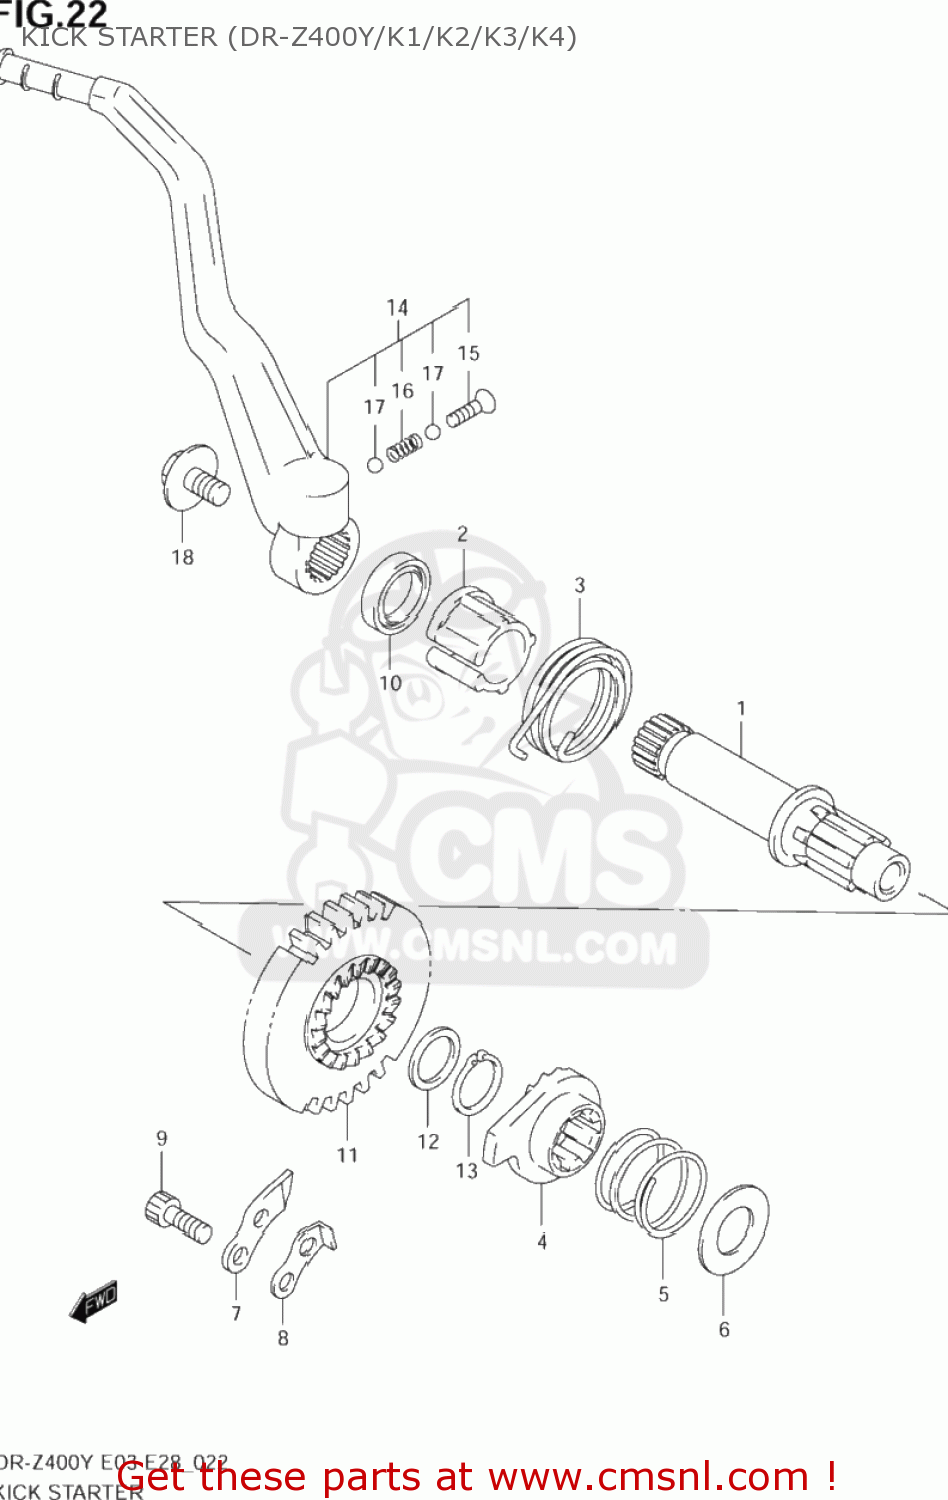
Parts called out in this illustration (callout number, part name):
1	SHAFT,KICK STARTER
2	GUIDE,KICK STARTER SFT SPRING
3	SPRING
4	STARTER,KICK
5	SPRING
6	SHIM(17X32X1)
7	GUIDE,KICK STARTER
8	STOPPER,KICK STARTER
9	BOLT,STRANGER
10	SEAL,OIL(20X27X6)
11	GEAR,KICK STARTER DRIVE
12	SHIM(22X28X1)
13	CIRCLIP
14	LEVER ASSY,KICK STARTER
15	SCREW(6X27.5)
16	SPRING
17	BALL
18	BOLT(8X14)
